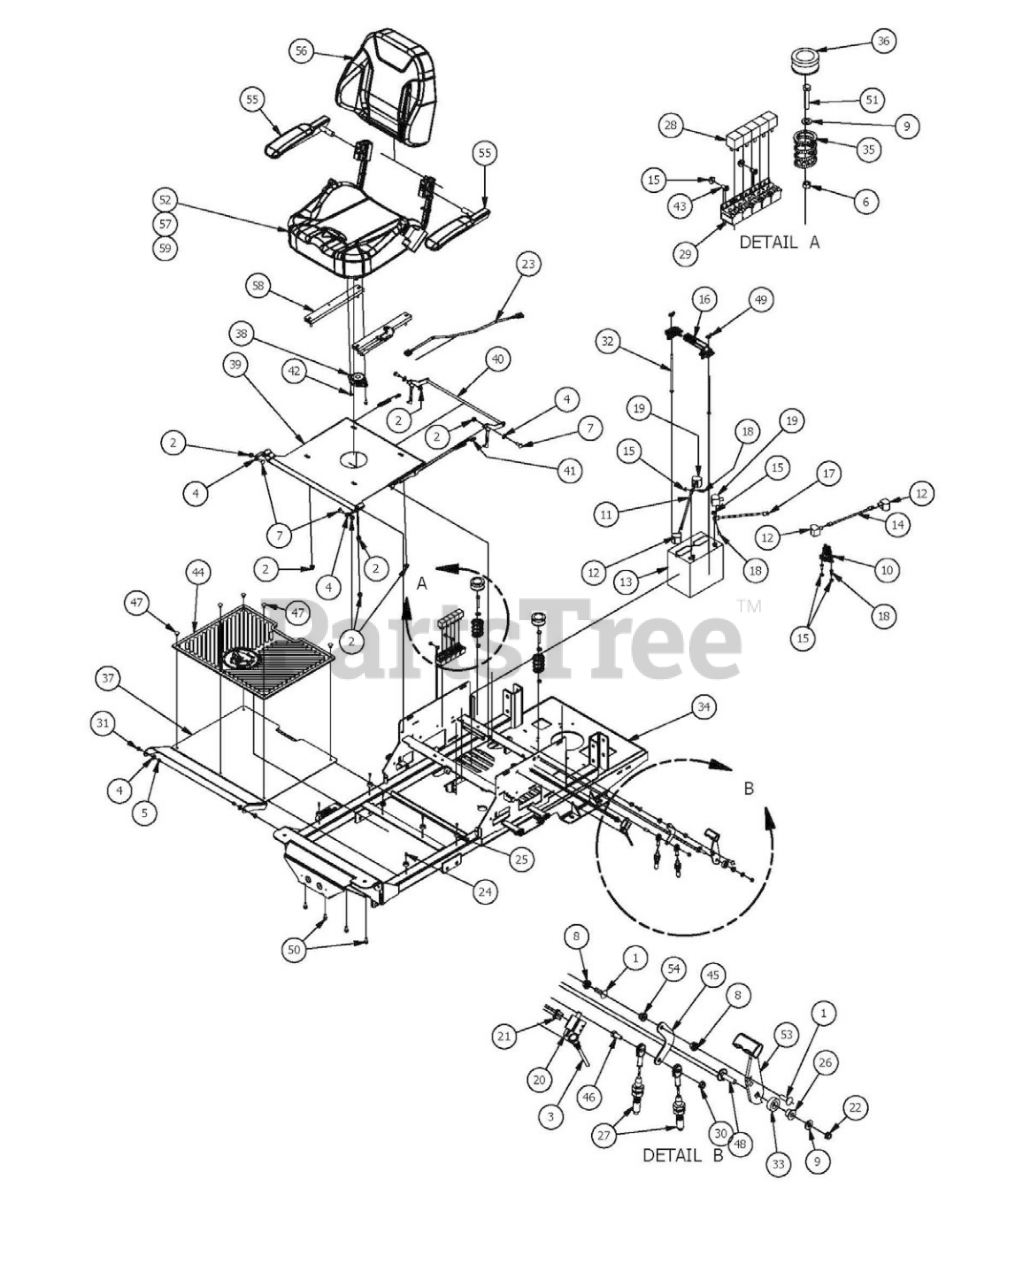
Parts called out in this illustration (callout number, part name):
1	5/16" x 1" Carriage Bolt
2	5/16" Nylock Flange Nut
4	.360 ID Plastic Washer
5	1/4" Nylock Nut
6	3/8-16 Hex Nuts Zinc
7	5/16" x 7/8" Carriage Bolt
8	5/16" Flange Nut
9	3/8" Flat Washer
11	24" Red Battery Cable
14	12 in red battery cable
15	1/4-20 Hex Flange Nuts Zinc w/Serrations
16	Battery Hold Down
17	Ground Cable
18	1/4" x 3/4" Hex Bolt
19	Black Boot For Ground Cable
20	Safety Switch
21	12-24x 1/2 HWH Bolt
22	3/8-16 Centerlock Half Nut
23	Seat Switch Adapter
24	#10 x 1/2" Self Tapping Screw
25	Button Bumper
26	Bronze Bushing SF-1220-8
27	Brake Cable
29	Wire Hamess
30	5/16-18 Nylock Jam Nut 1/2 Nut
31	1/4" x 3/4" Carriage Bolt
32	1/4-20 X8 Carriage Bolt
33	2015 Brake Lever Spacer
34	2016 Frame
35	Seat Spring
36	Seat Spring Cap Cover
37	Maverick Floorboard
38	Seat Safety Switch
39	Seat Plate 2016
40	Seat Latch Rod Assembly
41	Seat Latch Spring
42	1/4-20x1/2 HWH Bolt Slot
43	1/4" x 1/2" BS C/S 18-8 SS
44	Maverick Floor Mat
45	Brake Cable Adapter Bracket
46	5/16" x 3/4" Hex Bolt
47	5/8" Christmas Tree Fastener
48	3/8" x 1-1/4" Carriage Bolt
49	1/4" Wing Nut
50	5/16 x 3/4 washer head type F screw
51	3/8"-16 x 2" Gr 5 Hex Bolt
52	2017 Maverick Seat
53	Brake Handle
54	5/16-18 Nylon Insert Flange Nut (Black Cap)
55	Seat Arm Pair
56	Seat Back Cushion
57	Seat Cushion
58	Seat Rails
